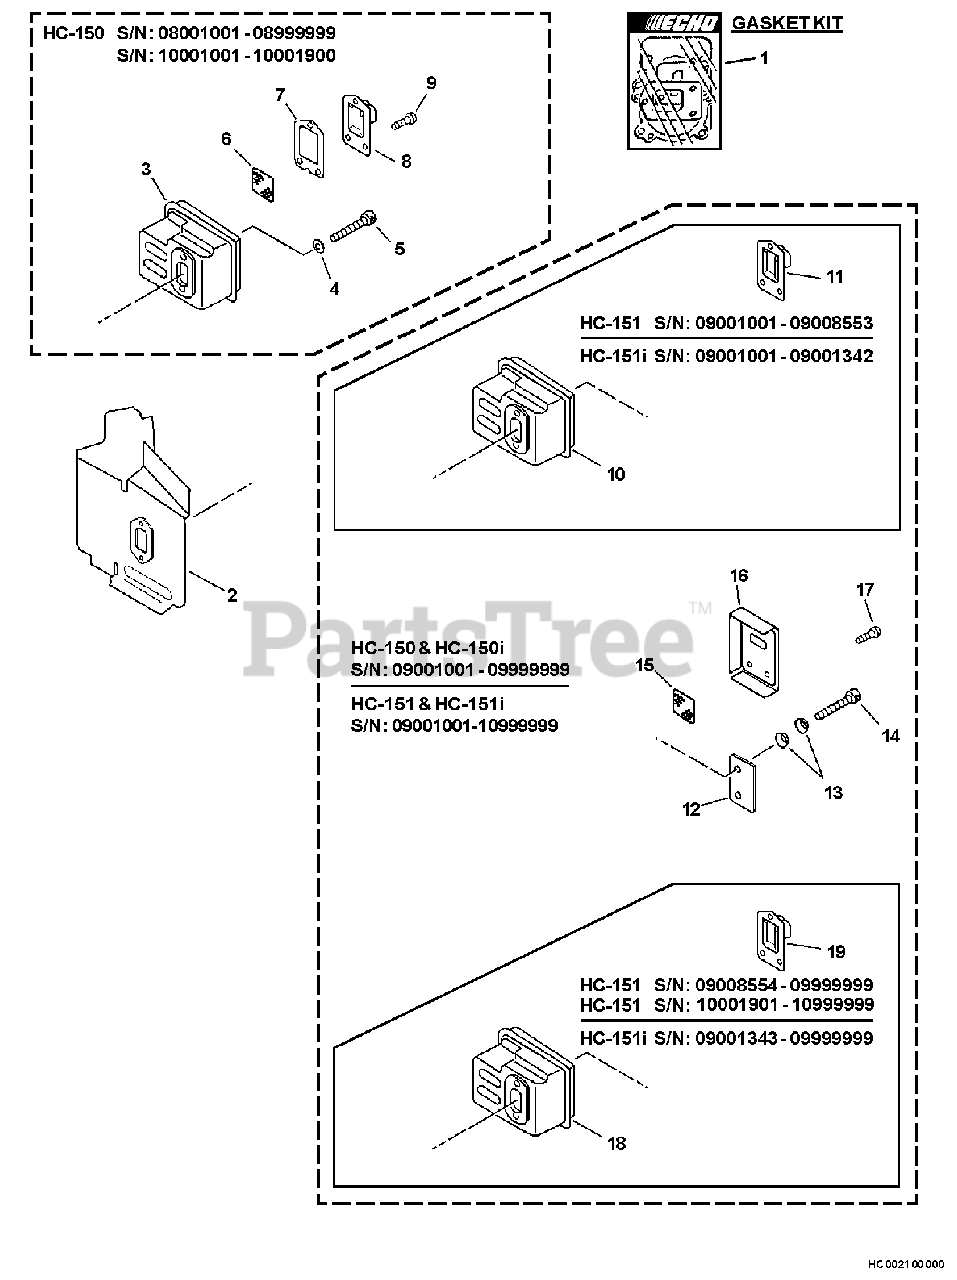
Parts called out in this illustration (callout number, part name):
1	GASKET KIT
2	HEAT SHIELD, EXHAUST
4	WASHER, FLAT 5.5×10×0.8
5	BOLT M5×50
6	SCREEN, SPARK ARRESTER
7	GASKET, EXHAUST
8	GUIDE, EXHAUST
9	SCREW 4×10
10	MUFFLER
11	GUIDE, EXHAUST
12	PLATE, EYE
13	CONICAL WASHER
14	BOLT 5×55
15	SCREEN, SPARK ARRESTER
16	GASKET, EXHAUST
17	SCREW 4×12
18	MUFFLER
19	GUIDE, EXHAUST
